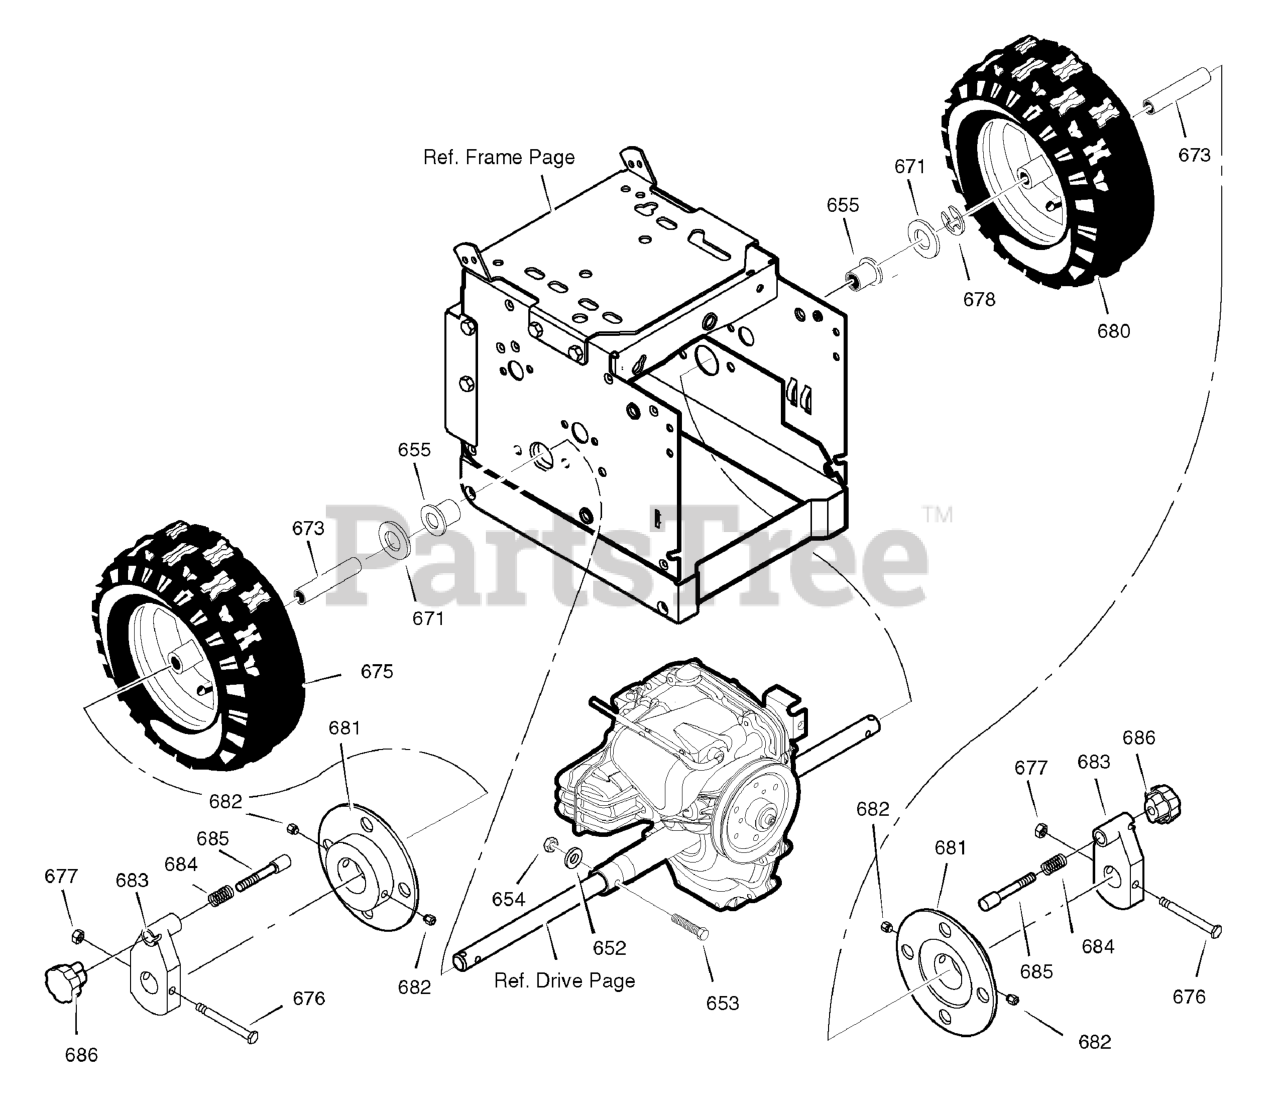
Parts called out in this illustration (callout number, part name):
650	SHAFT, AXLE
652	SPROCKET & HUB
653	SCREW, 1/4-20 X 1.75
654	NUT, 1/4-20 HEX NYLOCK
655	BEARING, AXLE
671	FLATWASHER
673	BUSHING, WHEEL
675	TIRE & RIM, RIGHT
676	SCREW, 1/4-20 X 1.75 HH
677	NUT, 1/4-20 HEX NYLOCK
678	RING, RETAINER
679	PIN, KLIK .25 X 1.38 DIA
680	TIRE & RIM, LEFT
